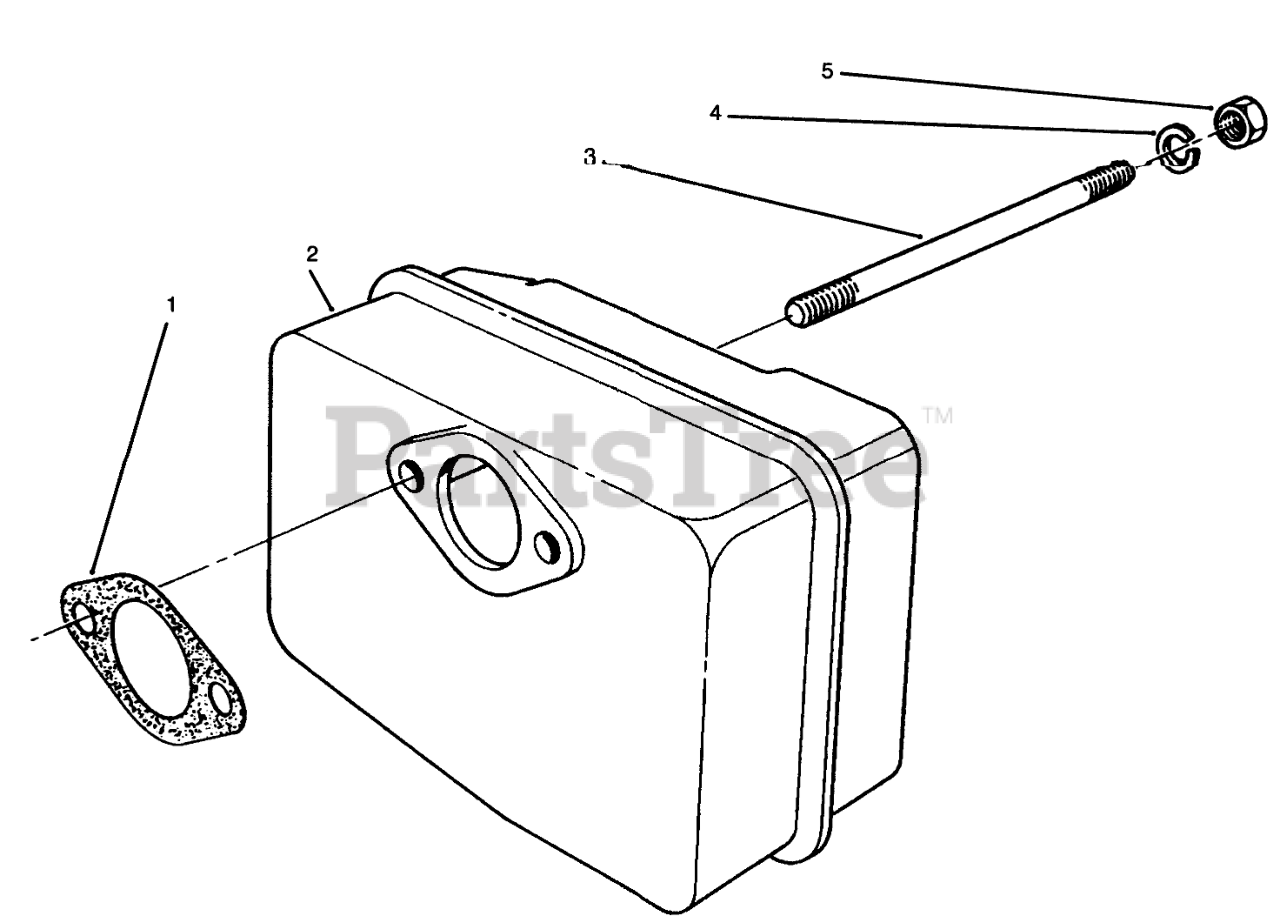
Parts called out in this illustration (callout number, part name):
1	GASKET
2	MUFFLER
4	WASHER-LOCK
